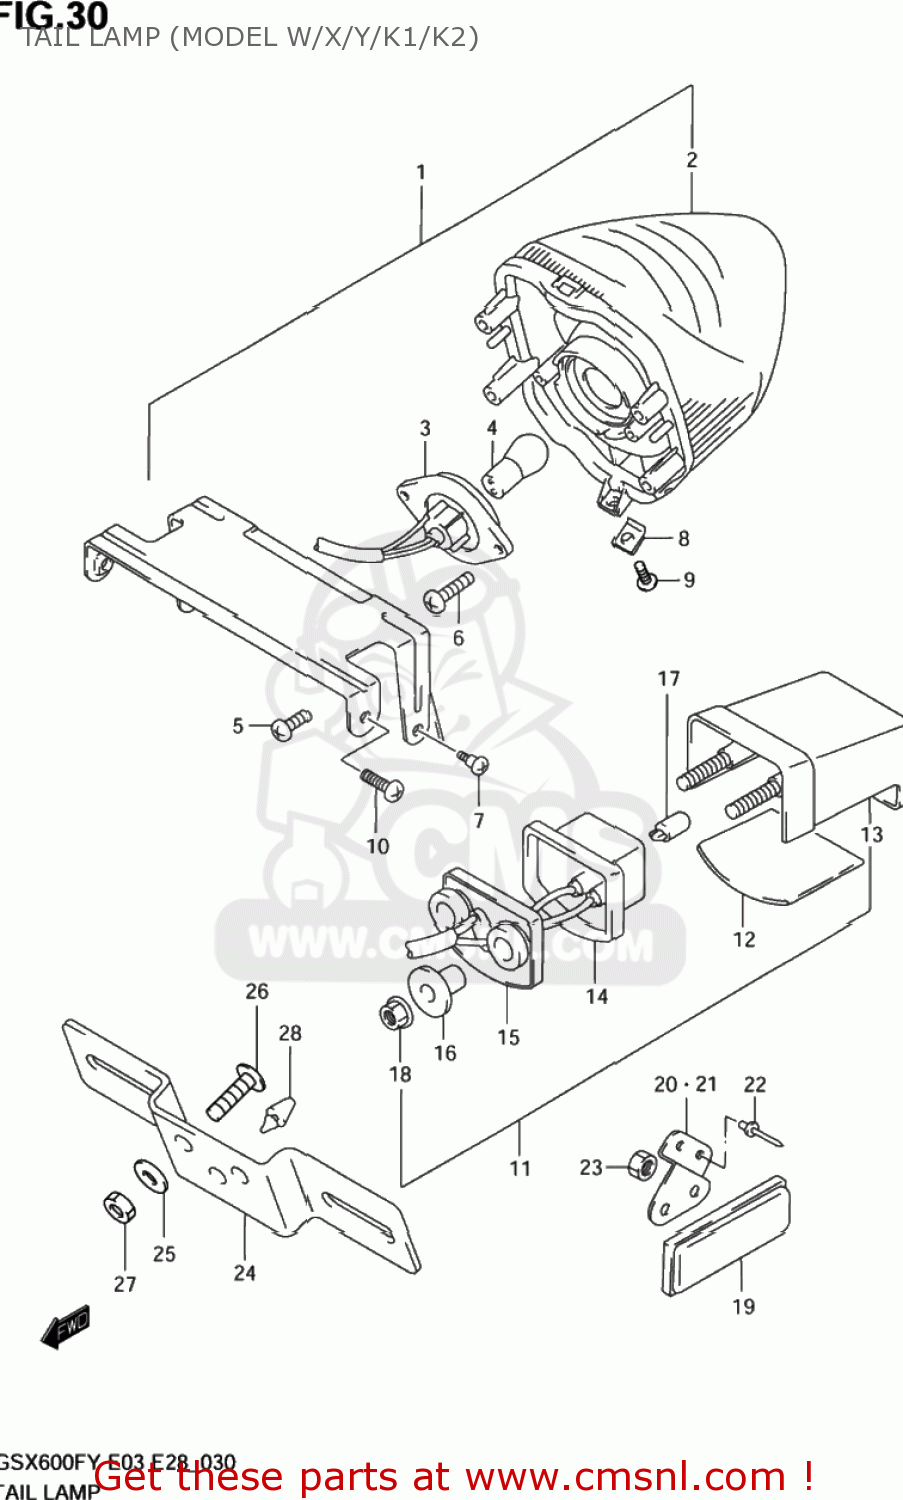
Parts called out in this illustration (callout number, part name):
1	LAMP ASSY,RR COMBINATION
2	LAMP UNIT
3	SOCKET & CORD
4	BULB(12V21/5W)
5	SCREW
6	SCREW
7	SCREW(5X12.8)
8	NUT
9	SCREW
10	SCREW
11	LAMP ASSY,LICENSE PLATE
12	LENS
13	COVER
14	HOUSING
15	SOCKET & CORD
16	SPACER
17	BULB(12V5W)
18	NUT
19	REFLECTOR ASSEMBLY,REAR
20	BRACKET,RR SIDE REFLECTOR,R
21	BRACKET,RR SIDE REFLECTOR,L
22	RIVET
23	NUT
24	BRACKET,LICENSE PLATE
25	WASHER(6.5X20X1.6)
26	SCREW
27	NUT 6MM
28	CUSHION
